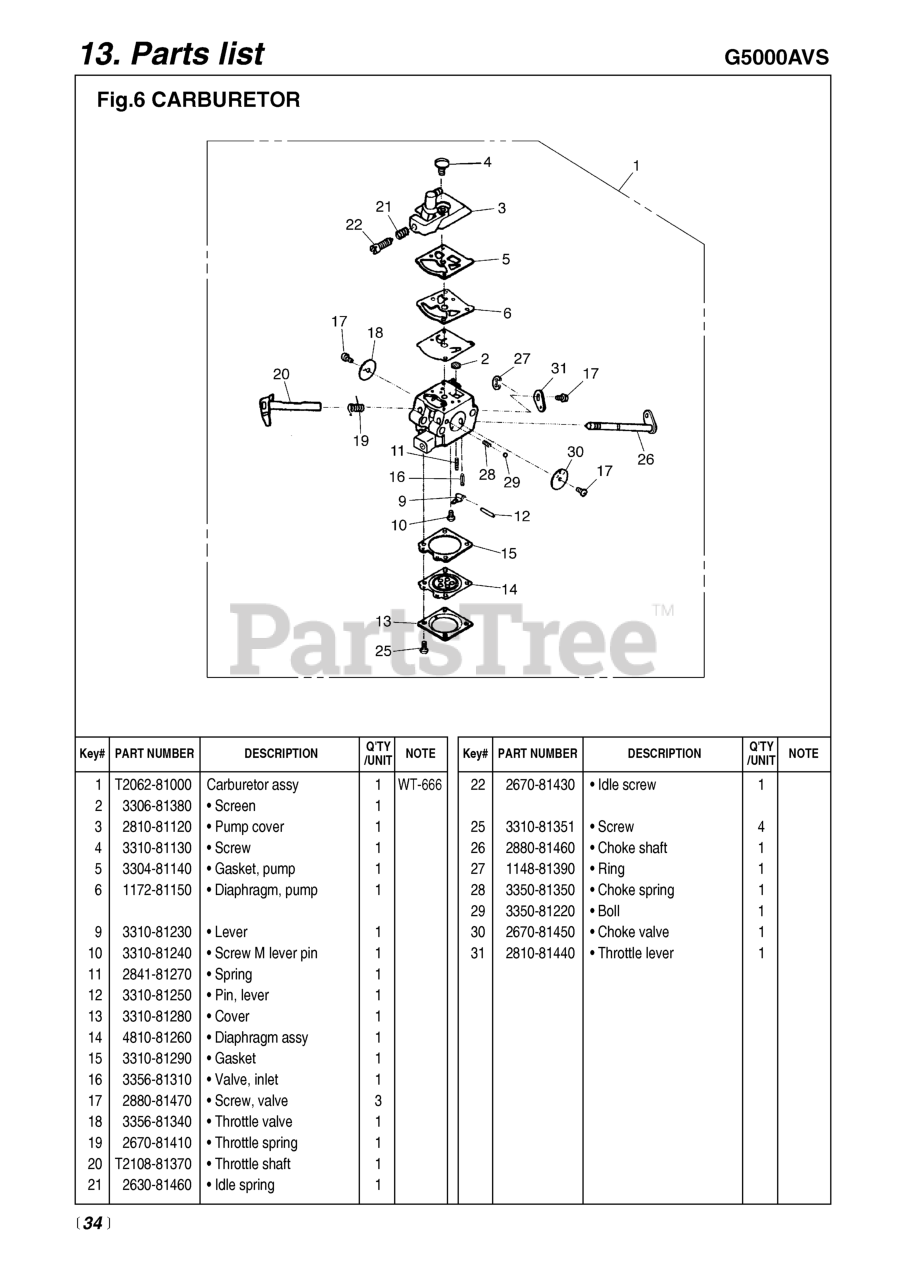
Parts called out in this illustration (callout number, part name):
1	CARBURETOR ASSEMBLY (WT-666-1)
3	COVER ASSEMBLY
5	GASKET, PUMP
6	DIAPHRAGM, PUMP
9	LEVER
11	SPRING (USE 2867-81270)
12	PIN, METERING LEVER
14	DIAPHRAGM (RPLS 3310-81260)
16	VALVE, INLET
17	SCREW (RPLS 3310-81360)
18	VALVE, THROTTLE
19	SPRING, RETURN
20	SHAFT ASSEMBLY, THROTTLE
21	SPRING, IDLE
25	SCREW ASSEMBLY
26	SHAFT, CHOKE
28	SPRING
29	BALL, FRICTION
30	VALVE, CHOKE
